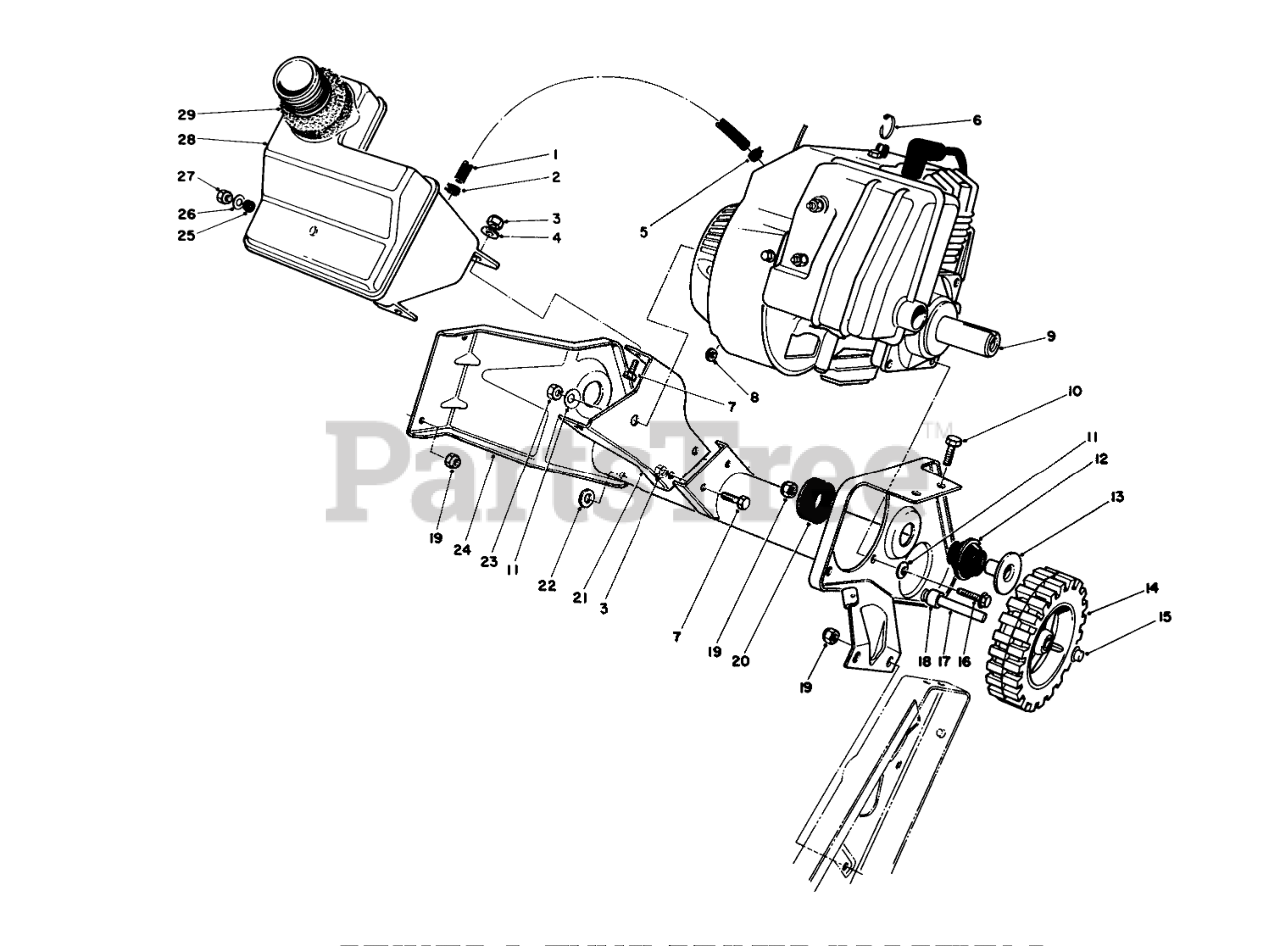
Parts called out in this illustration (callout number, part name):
1	GasLine
2	Clamp
3	NUT-LOCK, NI
4	WASHER-FLAT
5	CLAMP-HOSE
6	TIE-CABLE
7	SCREW-HH
8	SPACER-PLATE, PIVOT
9	Engine ASM
10	SCREW-HH
11	WASHER-BELLEVILLE
12	MOUNT-REBOUND
13	SPACER TUBE
14	WHEEL
15	RETAINER-PUSH ON
18	WHEEL SPACER
19	NUT-LOCK, NI
20	LOAD MOUNT
21	Support-Recoil
22	WASHER-FLAT
23	NUT (F/W & PPP)
24	Frame Assembly
25	GROMMET-RUBBER
26	WASHER-PLAIN
27	NUT-LOCK, CONE
28	Tank-Fuel (Incl. Ref. #25)
29	SEAL-FOAM
